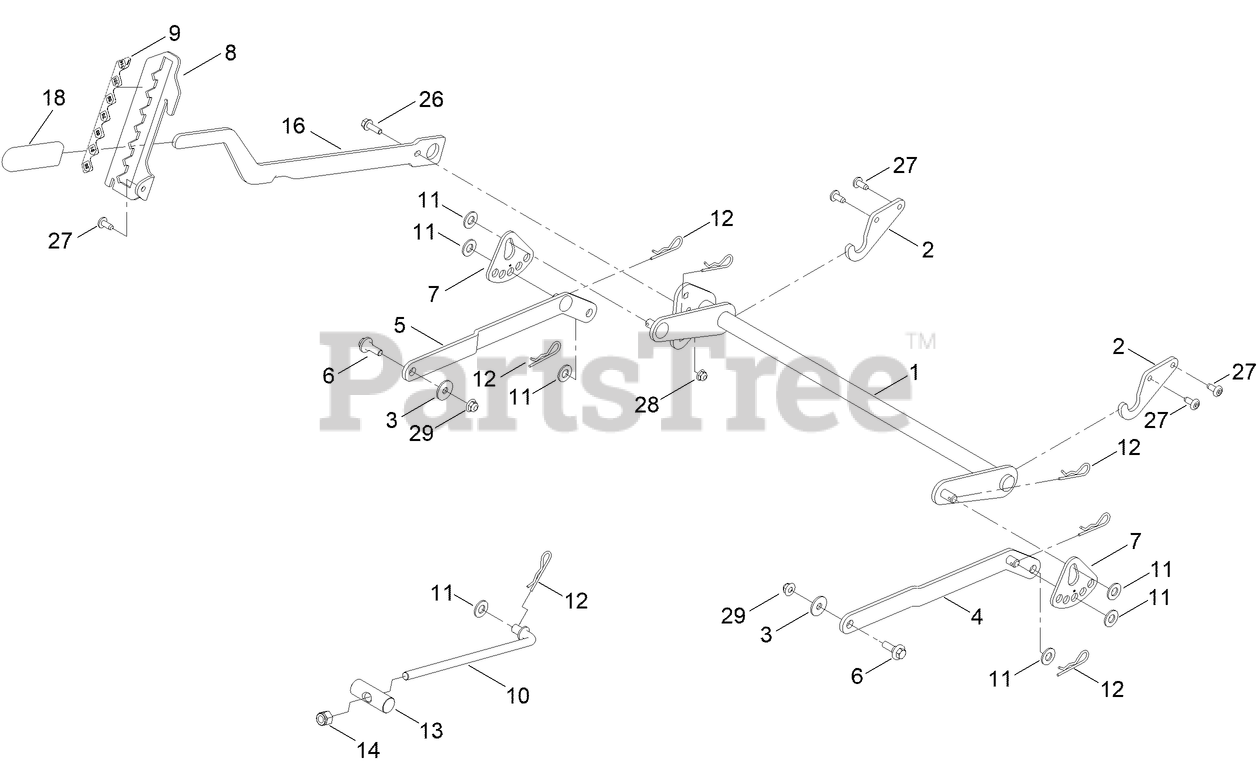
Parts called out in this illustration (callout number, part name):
1	DECK LIFT ASM
2	BRACKET-PIVOT, DECKLIFT
3	WASHER-HARDENED, CZ
4	LH ARM ASM
5	RH ARM ASM
6	SCREW-SHOULDER
7	PLATE-ADJUSTMENT, HOC
8	BRACKET-HOC
9	DECAL-HOC
10	ROD-MOUNT, DECK
11	WASHER-FLAT
12	PIN-HAIR
13	PIN-PIVOT
14	NUT-HEX
16	LEVER-LIFT
18	GRIP-LEVER
26	SCREW-HHF
28	NUT-HF
29	NUT-HF, NI
